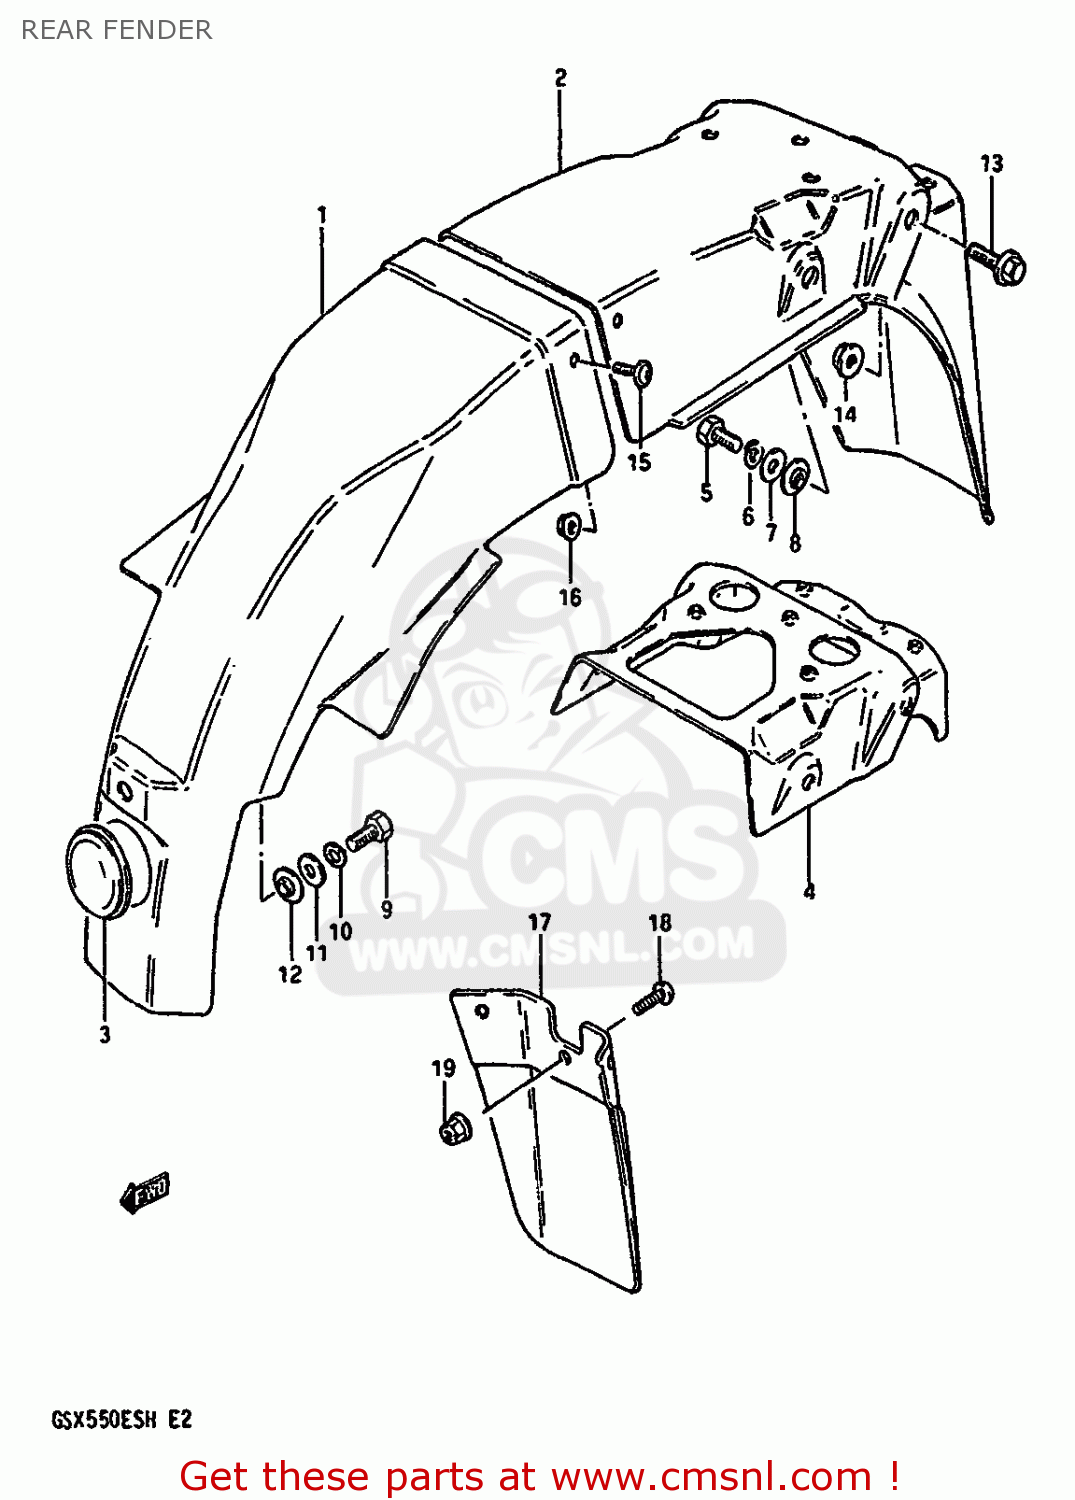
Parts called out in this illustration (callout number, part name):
1	BODY,REAR FENDER,FRONT
2	FENDER, REAR
3	GROMMET,REAR FENDER,FRONT
4	REINFORCEMENT,REAR
5	BOLT,8X16
6	LOCK WASHER
7	WASHER
8	WASHER
9	BOLT
10	WASHER,LOCK
11	WASHER 6MM
12	WASHER
13	BOLT
14	NUT
15	SCREW
16	NUT
17	EXTENSION
18	SCREW
19	NUT
